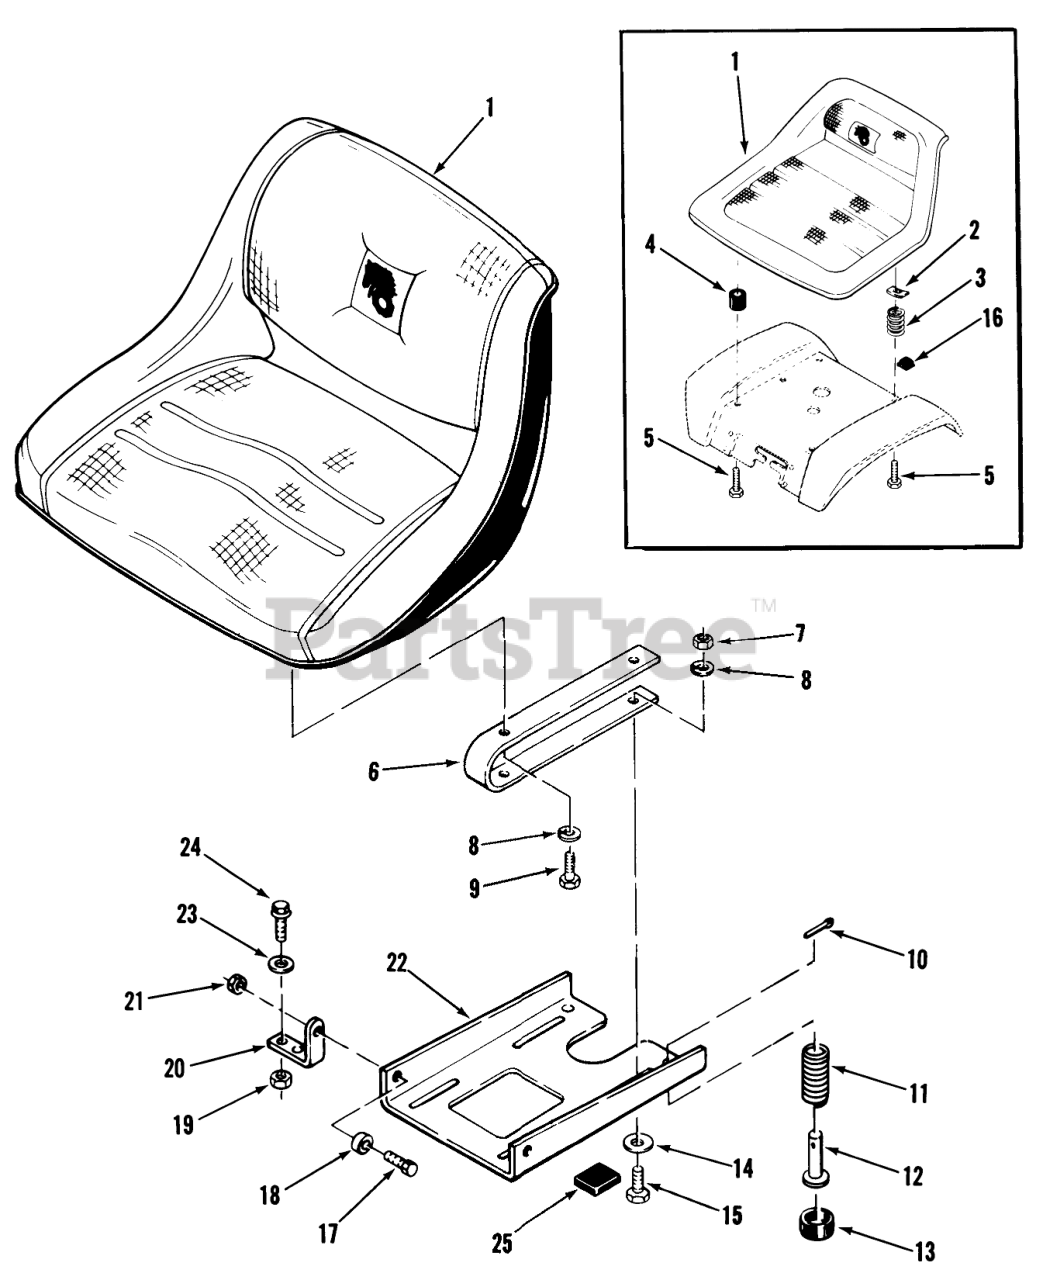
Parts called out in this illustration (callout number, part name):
1	Seat
1	Seat 312, 414
2	NUT-PUSH
3	SPRING
4	GROMMET-RUBBER
5	SPECIAL BOLT
5	HHCS
6	Spring
7	Nut
8	Lockwasher
9	HHCS
10	Cotter Pin
11	SPRING
14	WASHER 5/16 SAE
15	Bolt
16	BUMPER
17	HHCS
18	BUSHING
19	Nut
20	BRACKET-PIVOT
21	Nut
22	Pivot Plate
23	WASHER 5/16 SAE
24	Bolt
